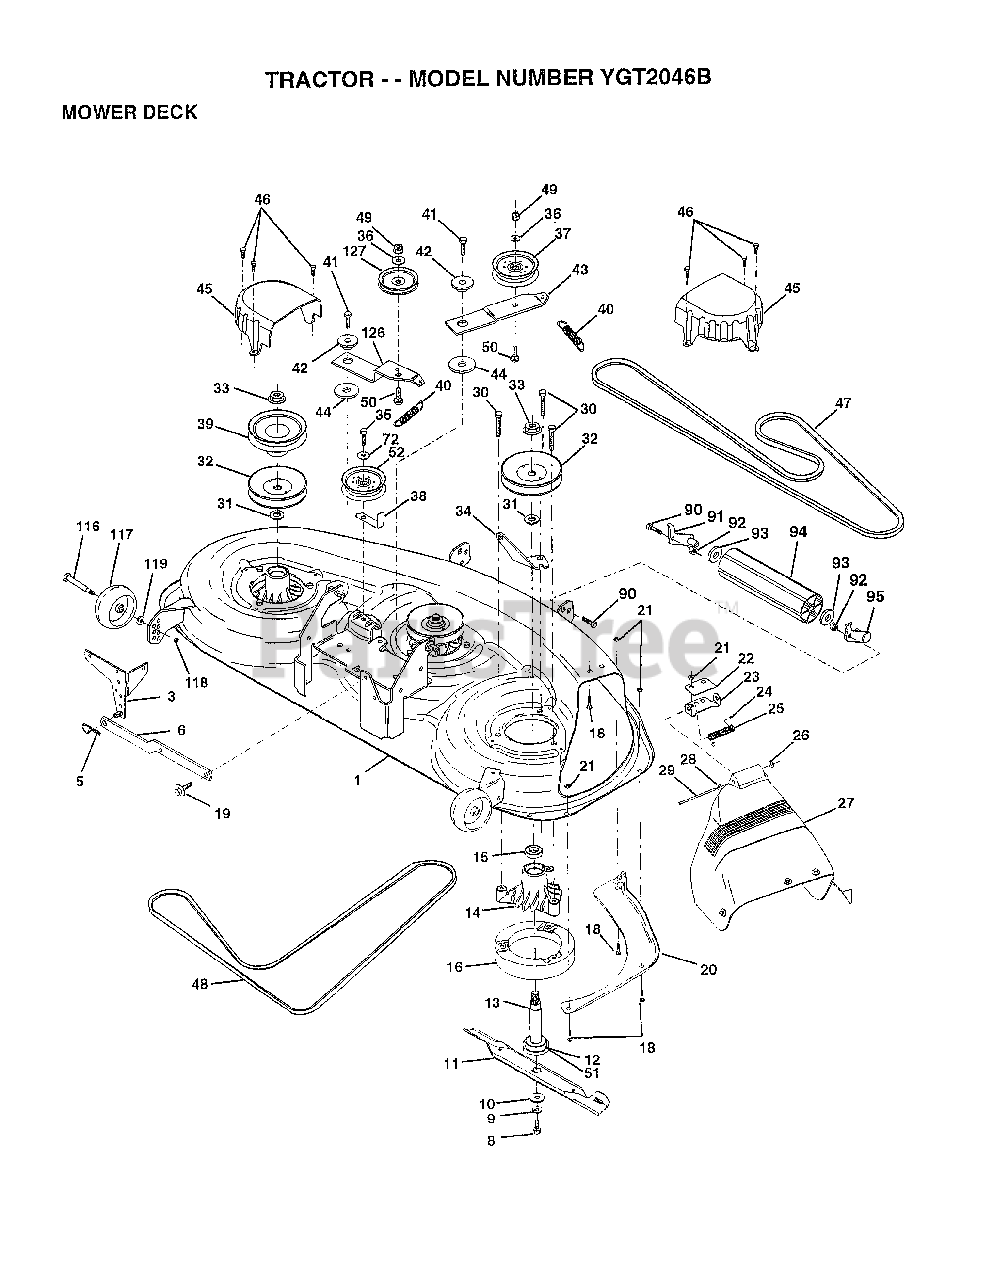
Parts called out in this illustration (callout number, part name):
1	"MOWER ASM 46"""
3	BRKT.ASM.SW.44/50
8	BLADE BOLT
10	WASHER.HARD.BLADE
11	"BLADE.HIGHLIFT46"""
12	BEARING.BALL
13	SHAFT.ASM.W/BRNG
14	HOUSING.MAND.44.V
15	BEARING
16	STRIPPER RND MWR
18	BOLT
19	BOLT SHD 5/16-18
20	BAFFFLE.VORTEX.46
22	STIFFENER BRKT
23	DEFLECTOR BRKT
27	SHIELD DEFLECTOR
28	WASHER
29	HINGE ROD
30	"SCREW-THD ROLL,WA"
31	WASHER
32	PULLEY.MAND.36/46
34	ANCHOR.SPRING.46
35	SCREW LT
36	WASHER
37	FLAT IDLER PULLEY
38	"KEEPER BELT,IDLER"
39	PULLEY.DRV.DCK.46
40	"SPRING.SEC.44""VEN"
41	SCREW
42	SPACER RETAINER
43	ARM.IDLER.DECK.46
44	HARDENED WASHER
45	COVER.MANDREL.46
46	SCREW.1/4-20X5/8
47	BELT-V.SEC.46.KEL
48	BELT V PRIM 50
50	BOLT.3/8-16X1.50
51	WASHER.FELT.
52	"PULLEY IDLER,FLAT"
72	WASHER HYT
90	BOLT
92	NUT
93	WASHER
116	BOLT.SHOULDER
117	WHEEL GAGE DONUT
118	LOCKNUT
119	WASHER
126	ARM.IDLER.PRIM.46
127	PULLEY.IDLER.4.25
